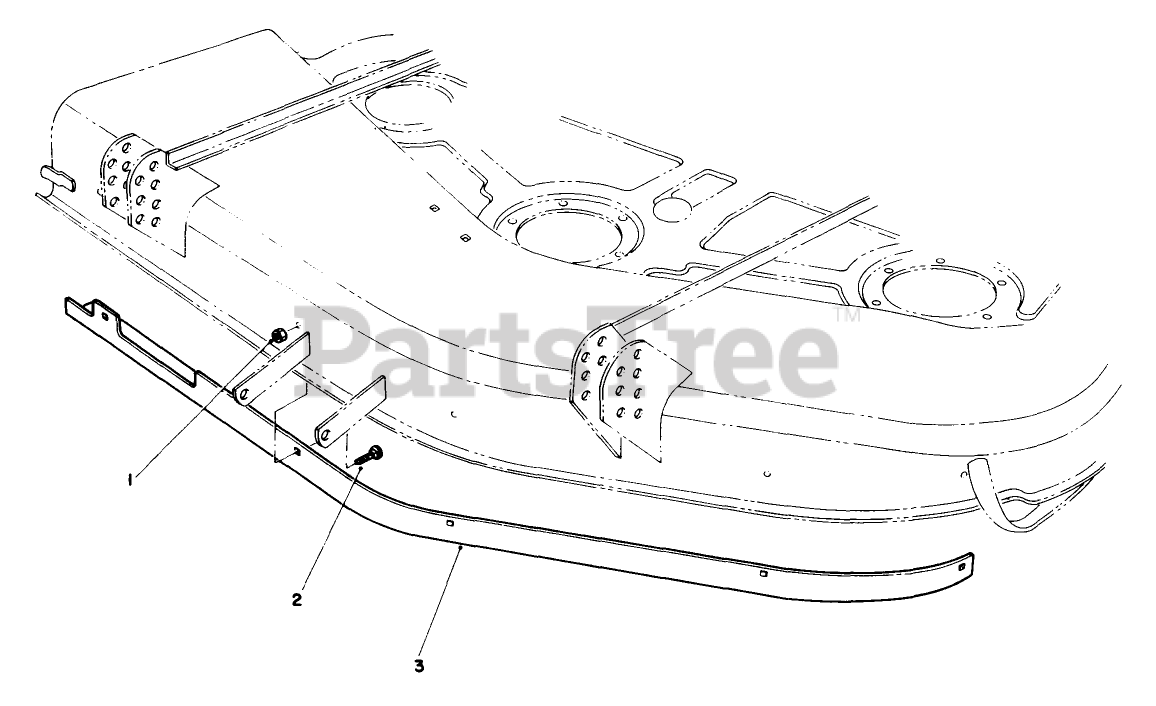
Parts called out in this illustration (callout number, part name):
1	NUT-LOCK, NI
2	SCREW-CARR
3	Baffle
